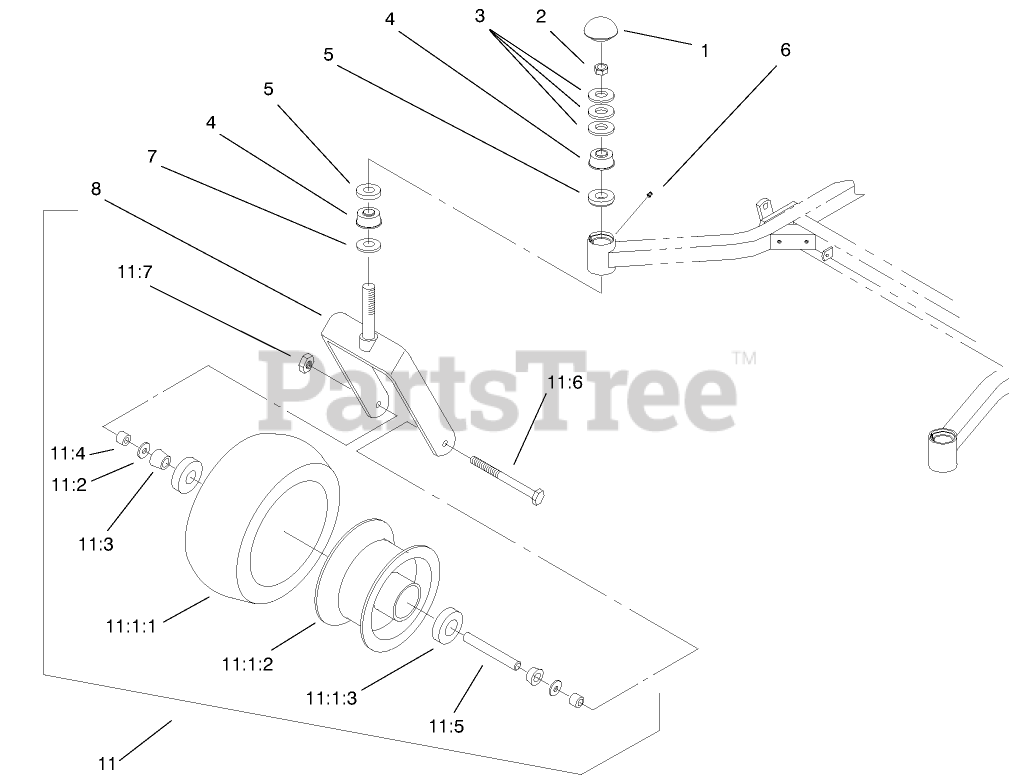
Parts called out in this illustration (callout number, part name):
1	Cap-Grease
2	LOCKNUT
3	Washer-Bellevue
4	BEARING-CONE, TAPERED
5	BEARING-CUP, TAPERED
6	Plug
7	Seal-Grease
8	Caster
11	Caster Wheel ASM
11:1:1	Tire
11:1:2	Wheel
11:1:3	BEARING-ROLLER, CUP
11:2	Seal-Bearing
11:3	BEARING-CONE
11:4	Spacer-Bearing
11:5	Spacer
11:6	Screw-HH
11:7	Nut-Lock
